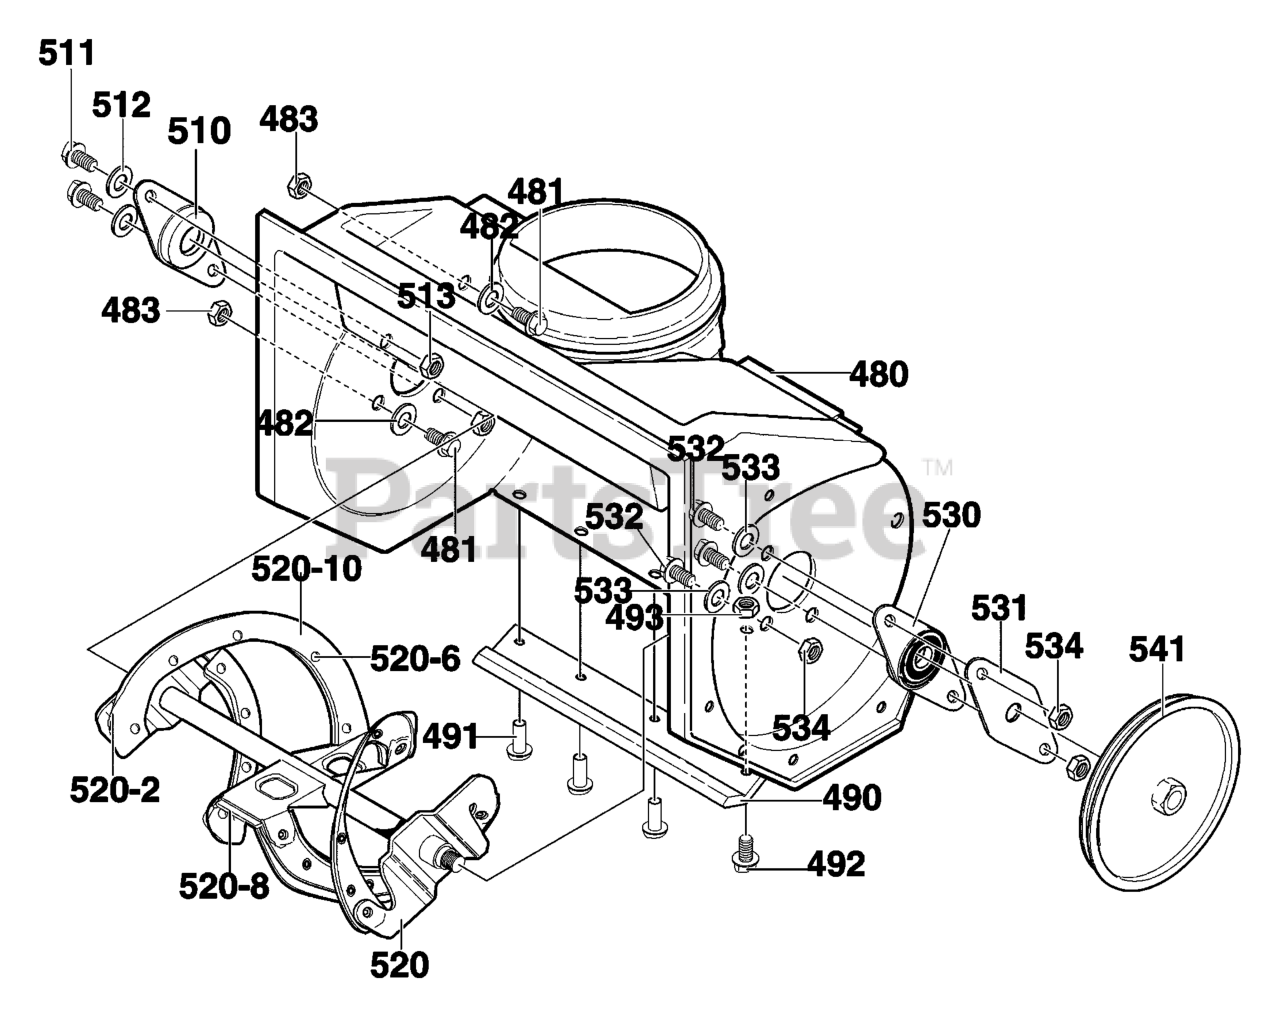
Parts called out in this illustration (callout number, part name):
480	HOUSING, ASSY
481	SCREW, 1/4-20X.75
482	WASHER, FLAT .281X.63X.065
483	NUT, 1/4-20 REGHEXCTRLK
490	BLADE, SCRAPER
491	RIVET, OVSET
492	SCREW, 1/4-20X.75
493	NUT, CNTRLK 1/4-20
510	BEARING, FLANGE
511	SCREW, 1/4-20X1.00
512	WASHER, FLAT .281X.63X.065
513	NUT, CNTRLK 1/4-20
520	AUGER, ASSY
520-2	BLADE, AUGER
520-6	RIVET
520-8	BLADE, CENTER
520-10	AUGER & BLADE SUPPORT
530	BEARING & PLATE ASSY.
531	PLATE, RETAINER
532	SCREW, 1/4-20X.63
533	WASHER, FLAT .281X.63X.065
534	NUT, 1/4-20 REGHEXCTRLK
541	PULLEY, V3L 6.00
